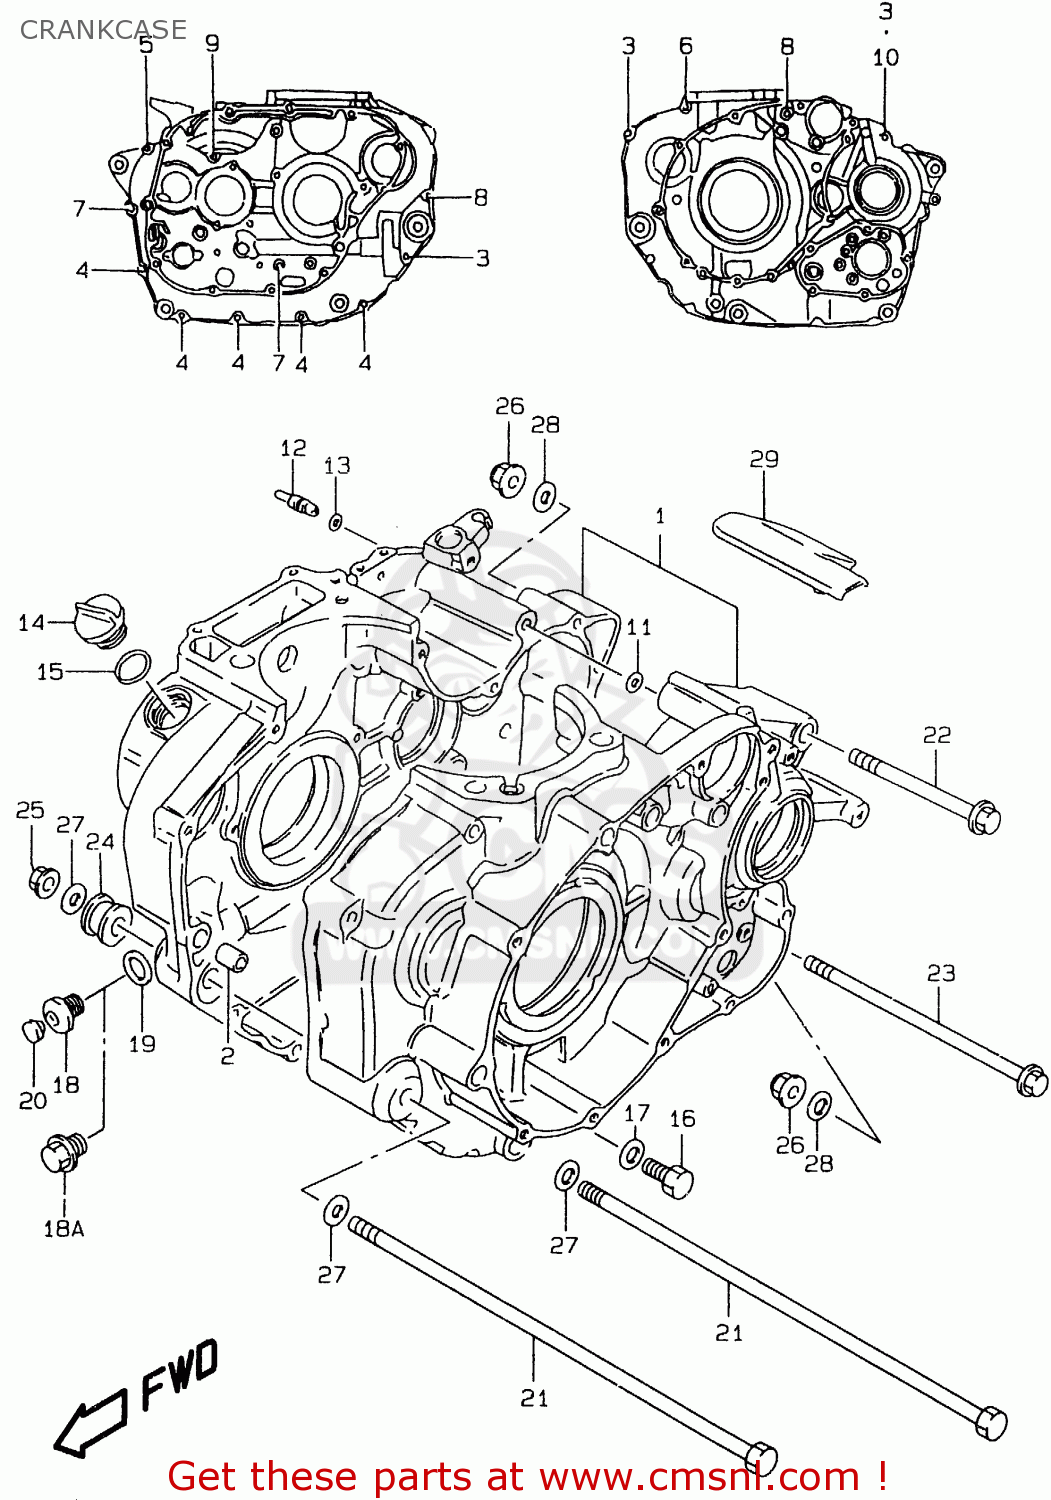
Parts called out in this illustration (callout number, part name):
1	CRANKCASE SET
2	PIN(8.4X11X20)
3	BOLT
4	BOLT
5	BOLT
6	BOLT
7	BOLT
8	BOLT
9	BOLT
10	GASKET(5.8X11X1.2) (NAS)
11	O RING(D:2.4,ID:9.6)
12	JET,OIL GALLERY(18)
13	O RING(D:1.2,ID:4)
14	PLUG(20X10)
15	O RING(D:3.1,ID:16.8)
16	BOLT
17	GASKET(12.1X16.2X3.7) (NAS)
18	PLUG,14X12
18A	PLUG(14X12)
19	GASKET(13.8X18.8X4.8) (NAS)
20	CAP(OD:12)
21	BOLT(10X323)
22	BOLT(10X105)
23	BOLT(10X180)
24	SPACER,ENGINE MOUNT(L20)
25	NUT
26	NUT
27	WASHER
28	WASHER
29	COVER,CRANKCASE START MOT
